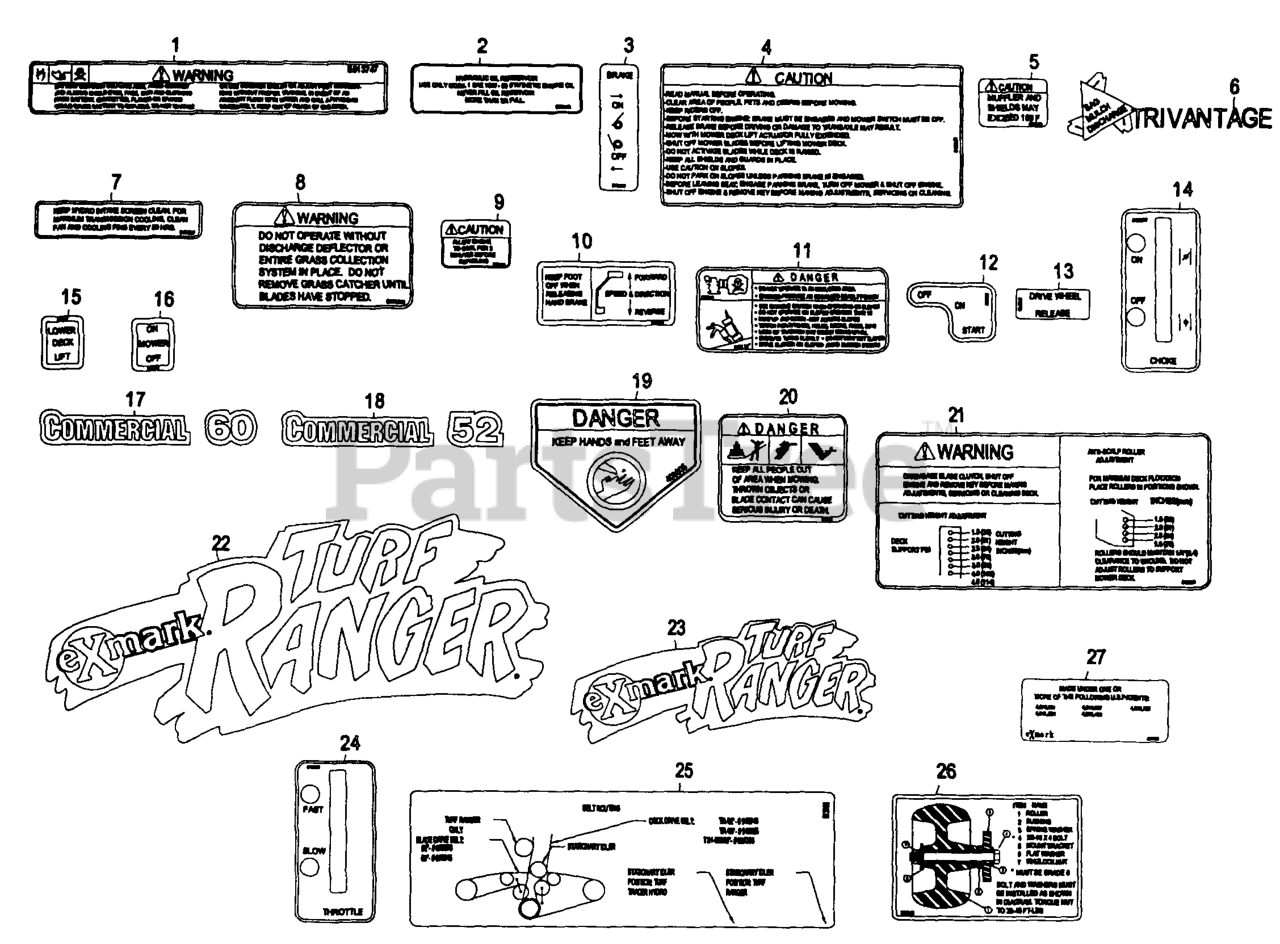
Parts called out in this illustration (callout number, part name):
1	DECAL-BATTERY
2	DECAL,HYDRAULIC TANK
7	DECAL,INTAKE
8	DECAL-WARNING, DISCHARGE
10	DECAL,FOOT PEDAL
11	DECAL,DANGER
15	DECAL-DECK LIFT
16	DECAL-MOWER SWITCH
17	DECAL,COMMERCIAL 60
18	DECAL,COMMERCIAL 52
19	DECAL-DANGER
20	DECAL-DANGER
22	DECAL,SWASH RANGER
25	DECAL,BELT ROUTING
26	DECAL,ROLLER MOUNTING
